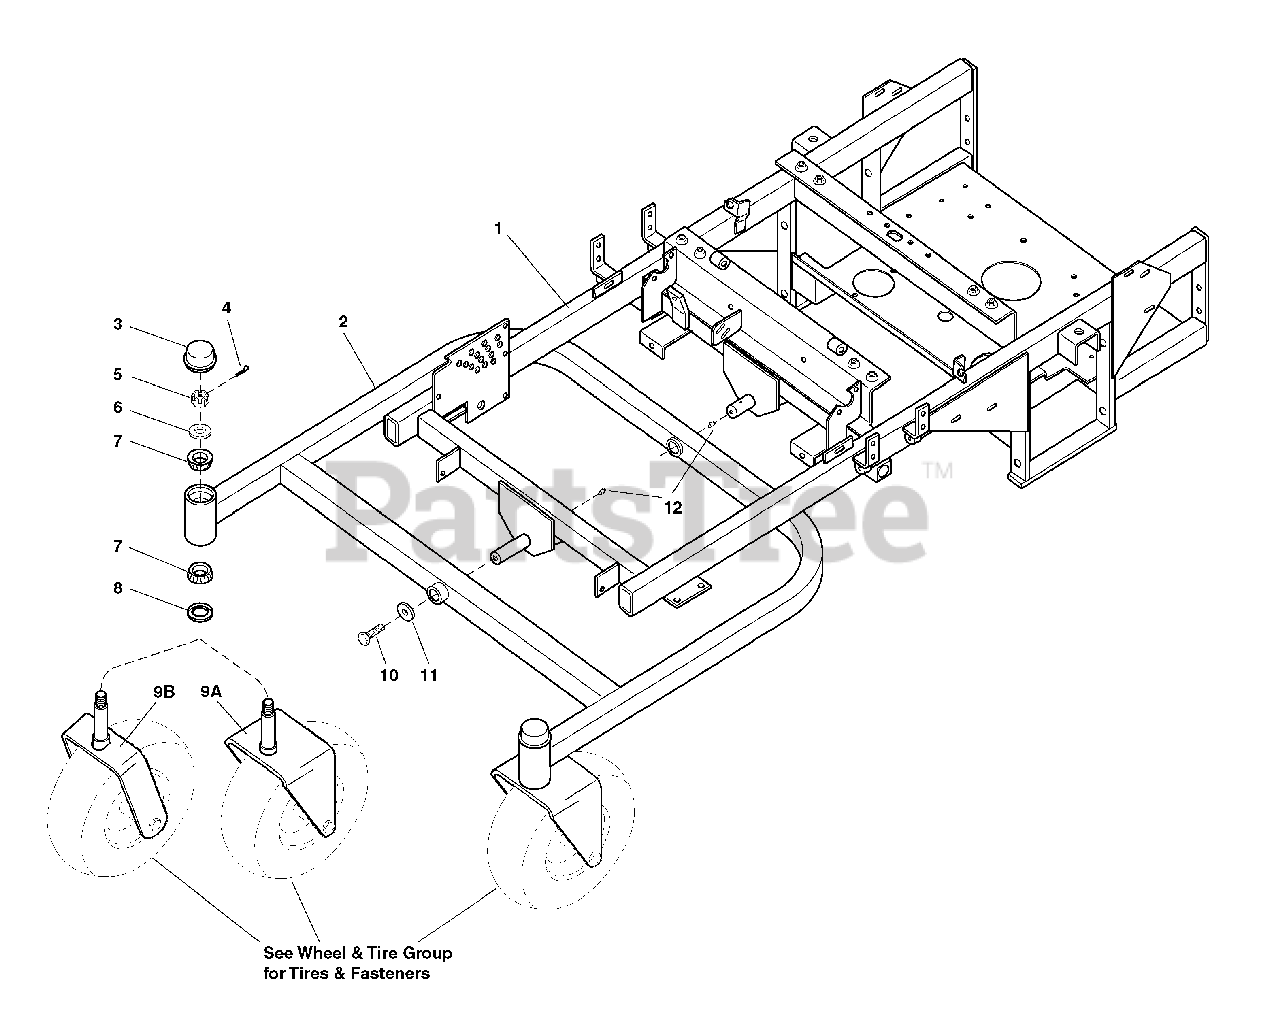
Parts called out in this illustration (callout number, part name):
1	MAIN FRAME
2	FRONT PIVOT FRAME
5	NUT, Hex, Slotted, 3/4-16
6	WASHER, 3/4
7	BEARING, Tapered Roller
8	SEAL, Grease
9A	YOKE, Caster (Serial No. 101-200)
9B	YOKE, Caster (Serial No. 201 & up)
10	CAPSCREW, Hex Hd, 1/2-20 x 1-1/4
11	RETAINER, Frame
12	GREASE FITTING
